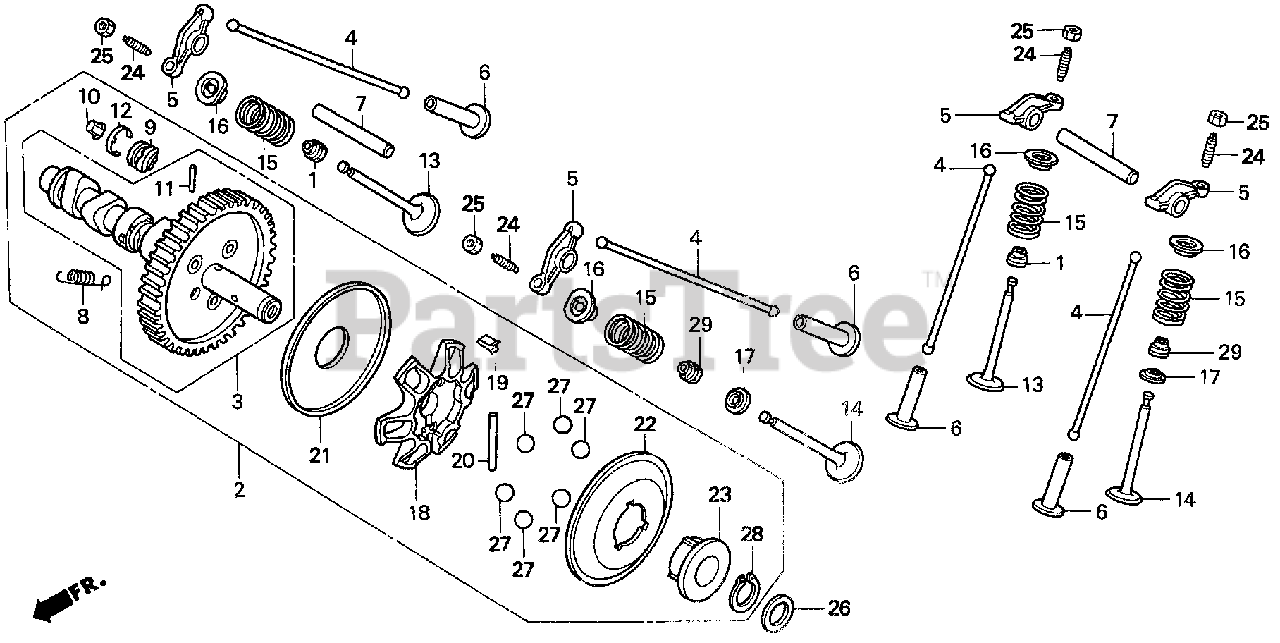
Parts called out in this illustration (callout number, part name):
1	SEAL, VALVE STEM
2	CAMSHAFT ASSY.
3	CAMSHAFT
4	ROD, PUSH
5	ARM, VALVE ROCKER
6	LIFTER, VALVE
7	SHAFT, ROCKER ARM
8	SPRING, WEIGHT RETURN
9	HOLDER, DECOMPRESSION PIN
10	PIN A, DECOMPRESSION
10	PIN B, DECOMPRESSION
10	PIN C, DECOMPRESSION (8.05)
10	PIN C, DECOMPRESSION
10	PIN D, DECOMPRESSION (8.15)
10	PIN D, DECOMPRESSION
10	PIN E, DECOMPRESSION (8.25)
10	PIN E, DECOMPRESSION
11	ROD, DECOMPRESSION
12	SPRING, DECOMPRESSION PIN HOLDER
13	VALVE, IN.
14	VALVE, EX.
15	SPRING, VALVE
16	RETAINER, IN. VALVE SPRING
17	SEAT, VALVE SPRING
18	HOLDER, GOVERNOR WEIGHT
19	PLATE, GOVERNER WEIGHT HOLDER
20	PIN, GOVERNOR WEIGHT HOLDER
21	PLATE, GOVERNOR (LOWER)
22	PLATE, GOVERNOR SLIDER
23	SLIDER, GOVERNOR
24	SCREW, TAPPET ADJ.
25	NUT, TAPPET ADJ.
26	WASHER, THRUST (17.2MM)
27	BALL, STEEL (18)
28	CIRCLIP (OUTER) (17MM)
29	SEAL, VALVE STEM
